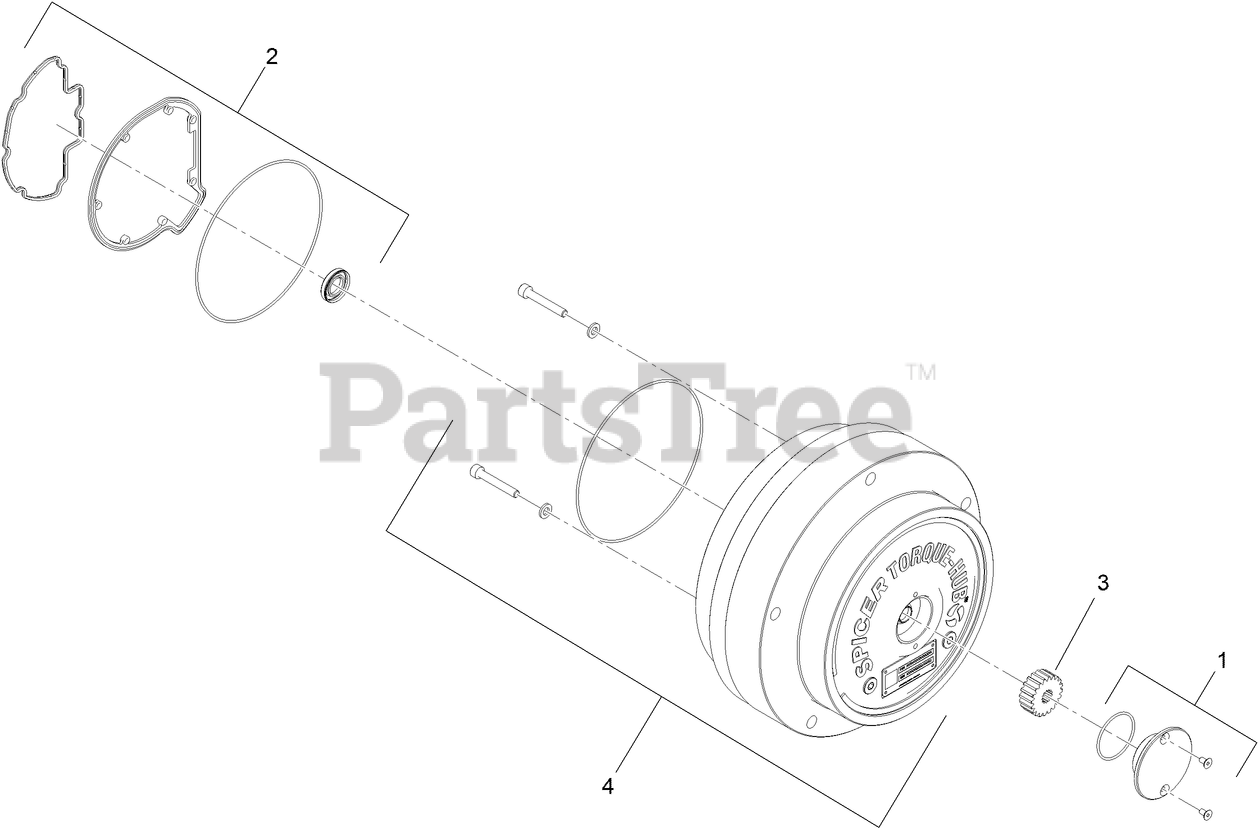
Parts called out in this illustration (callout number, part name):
1	KIT-COVER, SUN GEAR
2	KIT-SEAL, MAIN
3	GEAR-SUN
4	KIT-GEARBOX
